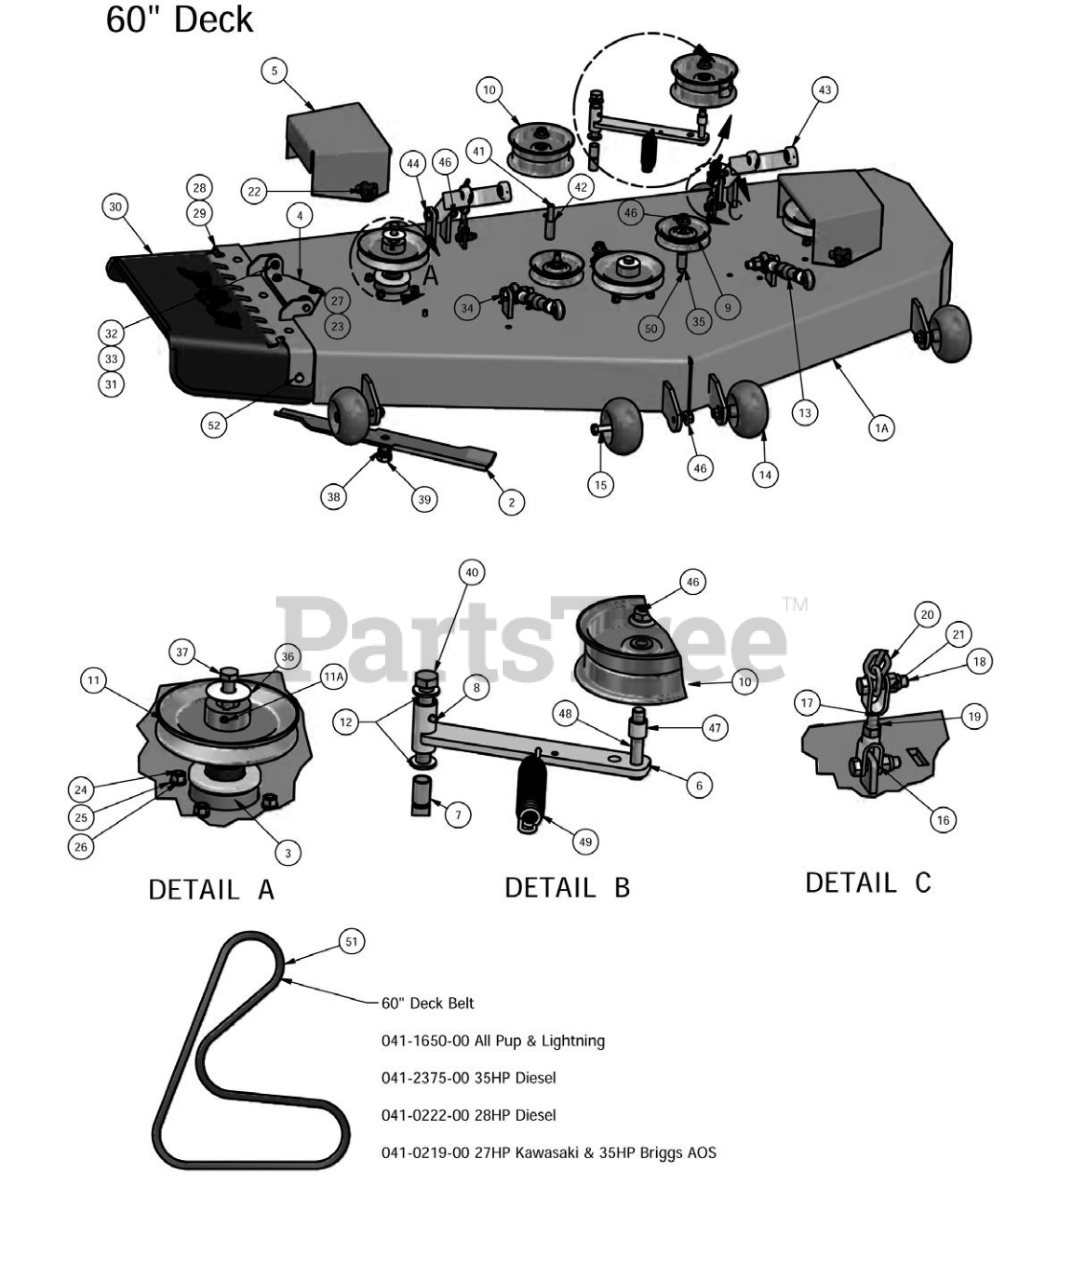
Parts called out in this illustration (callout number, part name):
1	60" Deck Complete Assembly with Spindles
1A	60" Deck Shell Only
2	60 Inch Fusion Blade
3	Double Bearing Spindle Assembly
4	Discharge Chute Hanger
5	Plastic Pulley Cover
6	Deck Idler 2009
7	5/8 x 1 1/8" Brass Bushing
8	1/4 Drive-in Grease Fitting
9	4 3/4" Idler Pulley
10	5 3/4" Deck Idler Pulley
11	6 1/4" Drive Pulley
11A	5/16" Set Screw
12	.635 ID Plastic Washer
13	Turnbuckle (Top Link)
14	Anti-Scalp Rollers
14A	Anti-Scalp Rollers Complete Assembly
15	1/2" x 4" Bolt (Grade 8)
16	Female Yoke
17A	4" Yoke & Chain Complete Assembly
17B	3" Yoke & Chain Complete Assembly
18	3/8" x 1 1/2" Hex Bolt
19	3/8" Hex Nut
20	4" Chain Assembly Lightning, AOS & Diesel
21	3/8 Nylock Nut
21A	3" Chain Assembly PUP (Only)
22	5/16" Knob
23	3/8" x 3/4" Hex Bolt
24	3/8" x 1 1/4" Hex Bolt
25	3/8" Lock Washer
26	3/8" Hex Nut
27	3/8" Flange Nut
28	60" Lower Hanger
29	60" Discharge Chute Upper Hanger Plate
30	Rubber Discharge Chute
31	.360 ID Plastic Washer
31A	Complete Assembly Rubber Discharge Chute
32	5/16" x 1" Hex Bolt
33	5/16" Nylock Flange Nut
34	5/8" x 2 1/2" Hex Bolt.
35	Pup Pulley Spacer
36	Cup Washer
37	1/2" x 1 1/2" Hex Bolt
38	5/8" Lock Washer
39	5/8-18 x 1 1/2 GR 8 Hex Bolt
40	5/8" x 4" Hex Bolt
41	1/2-13 x 3 1/2 GR 5 Hex Bolt
42	1 3/4" Pulley Spacer
43	Deck Arm Assembly
44	1/2" x 2 1/2" Hex Bolt
45	1/2" Flange Nut
46	1/2-13 Nylon Flange Nut-Orange
47	3/4 OD x 1/2 ID x 3\4 Length
48	1/2 x 3" Bolt
49	Deck Idler Spring
50	1/2 x 3 1/2 Flange Bolt Grade 8
51	Deck Belt All Pup & Lightning
51A	Deck Belt 35HP Diesel.
51B	Deck Belt 28HP Diesel
51C	Deck Belt 27HP Kawasaki & 35HP Briggs AOS
52	5/16" x 1 1/4" Carriage Bolt
